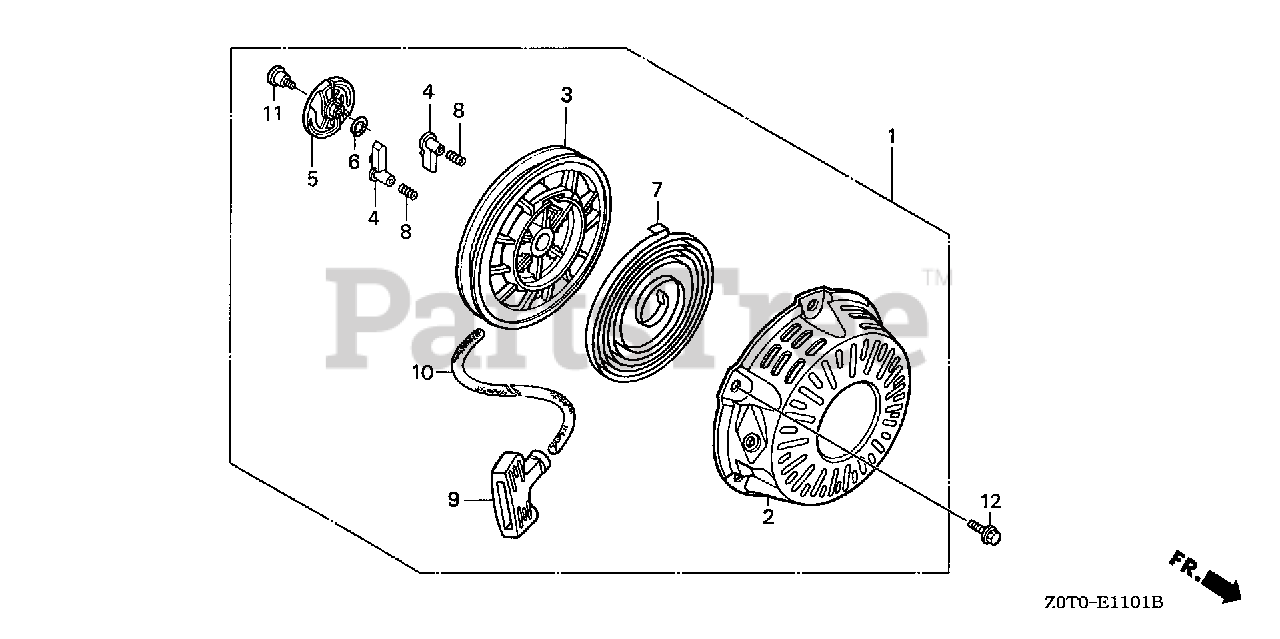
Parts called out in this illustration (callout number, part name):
1	STARTER ASSY., RECOIL *R280* (POWER RED)
1	STARTER ASSY., RECOIL *NH1* (BLACK)
2	CASE, RECOIL STARTER *R280* (POWER RED)
2	CASE, RECOIL STARTER *NH1* (BLACK)
3	REEL, RECOIL STARTER (NATURAL)
4	RATCHET, STARTER
5	GUIDE, RATCHET
6	SPRING, FRICTION
7	SPRING, RECOIL STARTER
8	SPRING, RETURN
9	GRIP, STARTER
9	KNOB, RECOIL SRARTER
10	ROPE, RECOIL STARTER
11	SCREW, SETTING
12	BOLT, FLANGE (6X10)
